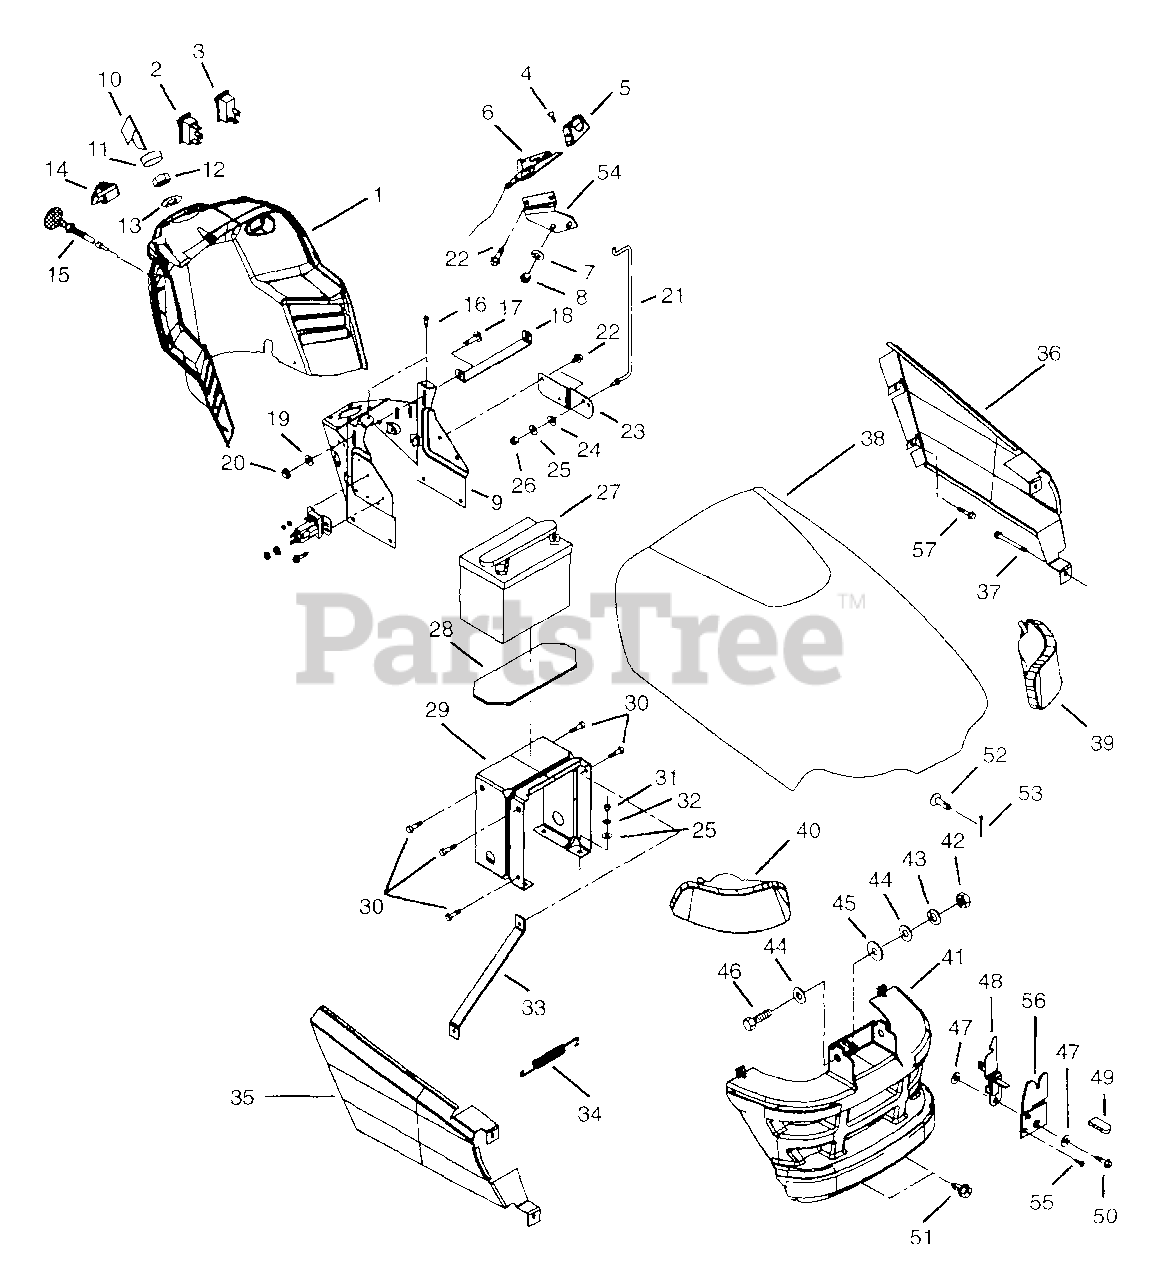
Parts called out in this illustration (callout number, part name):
1	DASH
2	SWITCH - CRUISE
3	SWITCH - LIGHT
4	SCR-SET 10-24X.38 UNC-3A
5	KNOB - THROTTLE
6	THROTTLE CONTROL-B&S
7	WSHR-FL-STL .323X.625X.062 PL
8	NUT-LK-CTR .250-20 PL
9	SUPPORT - DASH - TOP
10	KEY -W/CAP
11	CAP - IGNITION SWITCH
12	NUT- PANEL .562-24 GRECO
13	WSHR-LK-INT .563X.040 PL
14	PTO KNOB/SWITCH ASSY
15	CHOKE CABLE
16	SCR-TAP 10-24X.375 CRPH 1A
17	BLT-RDHDSQNK .312-18X.62SHTPL
18	HOLDDOWN - BATTERY
19	WSHR-FL-STL .323X.625X.062 PL
20	NUT-LK-NYL.312-18 PL
21	ROD - HOOD PROP
22	SCR-TAP .250-20X.37 HWH PL TR
23	MOUNT - PROP ROD
24	WAVE WASHER .390X.655X.110
25	WSHR-FL-STL.312X.734X.065PL
26	NUT-LK-CTR .250-20 PL
27	BATTERY
28	RUBBER PAD
29	SUPPORT DASH BASE
30	SCR-TAP .312-18X.50 HWH PL TR
31	NUT-HEX .312-18
32	WSHR-LK .312X.097 PL HVY
34	SG-TENS .035X.45X2.75 WLD 3.5
35	SIDE PANEL- RH
36	SIDE PANEL- LH
37	SCR-TAP 12-16X.500 HI-LOTPHBL
39	HEADLIGHT- LH
40	HEADLIGHT- RH
41	GRILLE
42	NUT-HEX .312-18
43	WSHR-LK .312X.097 PL HVY
44	WSHR-FL-STL .328X1.0X.094 PL
45	WSHR-PLASTIC .390X.875X.062
46	BLT-HEX .31-18X1.00 PL GR5
47	WSHR-FL-STL .281X1.250X.048PL
48	HOOD LATCH
49	GRIP .062 X .375 X 1.000 RE
50	SCR-TAP 12-24X.75 HWH PL TR
51	SCR-TAP .312-18X.75 HWH PL TR
52	PIN, CLEVIS .243/.248X1.50 YWZ
53	PIN-COTR .09X.75 PL
54	BRACE-THROTTLE CONTROL
55	SCR-TAP 10-12X.50 CRPH PL A BL
56	LOCATOR, HOOD
57	SCR-TAP 10-12X.62 CRPH PL A
